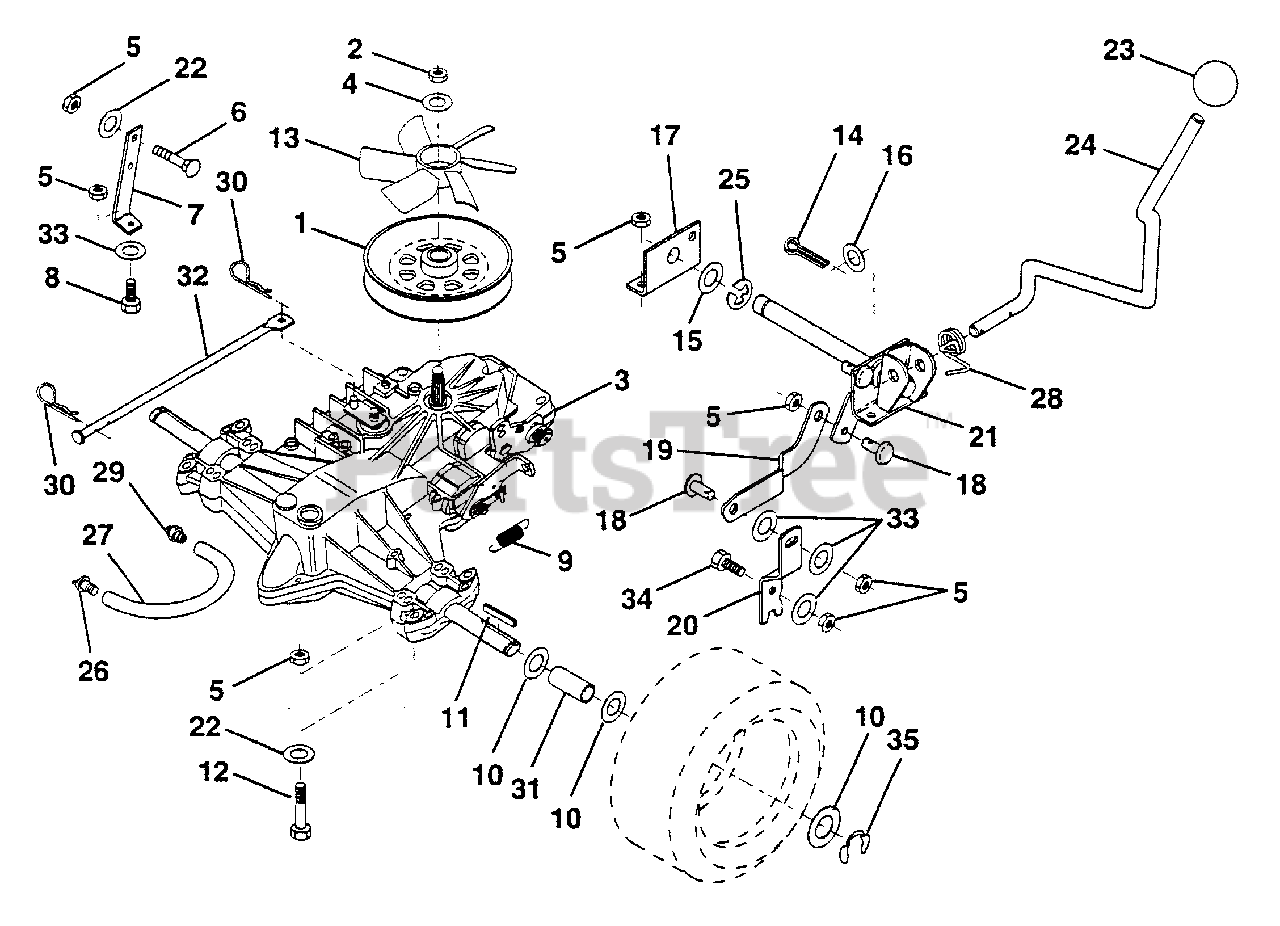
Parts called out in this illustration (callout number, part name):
2	Nut Lock 1/2-20 UNF x 3/4 x 7/16
3	Transaxle, Hydro 0310-0500
4	Washer 17/32 x 1-3/16 x 12 Ga.
5	Nut Lock Hex w/Ins. 5/16-18
6	Bolt, Carriage
7	Strap, Torque
8	Bolt Fin Hex 5/16-18 x 1-1/2
9	Spring Brake
10	Washer 25/32 x 1-1/4 x 16 Gauge
11	Key, Square
12	Bolt, Hex Head 5/16-18 x 2-1/2
13	Fan, Transaxle, Hydro
14	Pin, Cotter 1/8 x 1
15	Washer 21/32 x 1-1/4 x 13 Ga.
16	Washer 17/32 x 3/4 x 16 Ga.
17	Support, Shift Handle
19	Link, Shift
20	Lever, Shift
21	Pivot Shaft Assembly
22	Washer 11/32 x 11/16 x 16 Ga.
23	Knob, Shifter
24	Rod, Shifter
26	Cap, Vent Hose
27	Hose, Vent
28	Spring, Torsion
29	Nipple, Vent Hose
30	Retainer Spring
32	Actuator, Bypass, Hydro
33	Washer 11/32 x 3/4 16 Ga.
34	Bolt Hex Hd. 5/16-18 x 1
